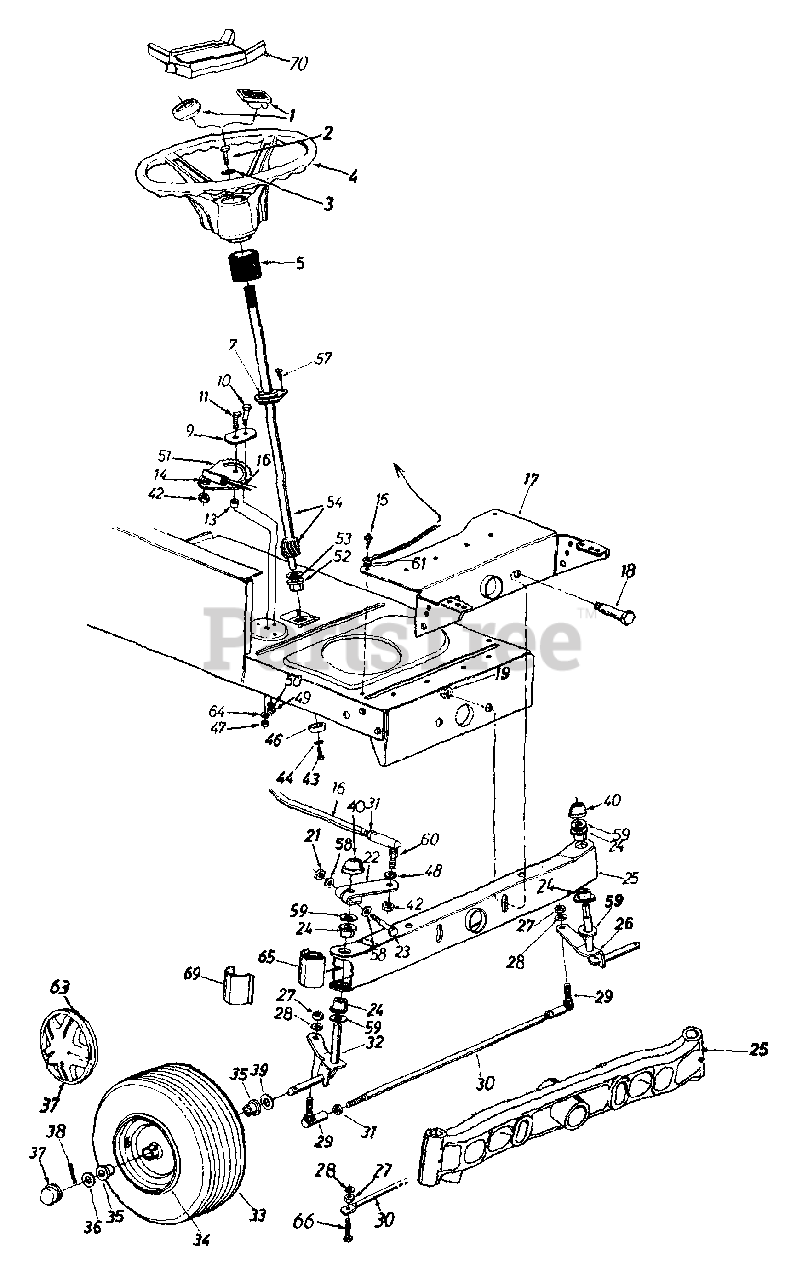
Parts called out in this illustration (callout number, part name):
1	Steering Wheel Cap
2	Hex Bolt 5/16-18 x 1" Lg.
3	Belleville Wash. .345" I.D.
4	Steering Wheel (3 Spoke)
5	Steering Bellow - 4.5"
7	Flange Bearing .628" I.D. x 1.36 O.D.
9	Retainer Plate
10	Shoulder Bolt .437 x .35 Lg. 5/16-18
11	Hex Bolt 3/8-24 x 1.0" Lg. (Gr. 5)
13	Spacer .380" I.D. x .625" O.D. x
14	L-Wash. 3/8" I.D. (H.D.)
15	Hex Wash. Hd. Self-Tap Scr.
16	Steering Drag Link
18	Shoulder Bolt
19	Flanged L- Nut 3/8-16 Thd.
21	Hex L-Nut 5/16-24 Thd.
22	Steering Arm Front Axle
23	Hex Bolt 5/16-24 x 2.00" Lg.
24	Hex Flg. Brg. .632 I.D.
26	Front Axle Ass'y. - L.H.
27	Hex Nut 3/8-24 Thd.
28	L-Wash. 3/8" I.D.
29	Ball Joint 3/8-24 Thd.
30	Tie Rod (Adjustable)
31	Hex Jam Nut 3/8-24 Thd.
32	Front Axle Ass'y. - R.H.
36	Fl-Wash. .635 I.D. x 1.59" O.D.
37	Front Wheel Hub Cap
38	Cotter Pin 1/8" Dia. x 1.25"
39	Fl-Wash. .640" I.D. x 1.24" O.D.
40	Push Cap 5/8" Dia. Rod
42	Hex Jam Nut 3/8-24 Thd.
43	Hex Patch Bolt 5/16-18 x .62"
44	Lockwasher 5/16
46	Cap
47	Hex Cent. L-Nut 3/8-24 Thd.
48	L-Wash. 3/8" I.D.
49	Hex Cent. L-Nut 5/16-18 Thd.
50	L-Wash. 5/16" I.D.
51	Steering Gear Segment
52	Hex Flg. Brg. .634 I.D.
53	Fl-Wash. (Hardened)
54	Steering Shaft
57	Oval Hd. Cr.- Sunk Scr. (Style A)
58	Wave-Wash. .32" I.D. x.62" O.D.
59	Fl-Wash. (Hardened)
60	Drag Link Ball Joint 7/16-20 Thd.
63	Spring Clip
64	Bell-Wash. .39" I.D. x 1.38" O.D.
65	Pivot Bar End Cap
66	Hex Bolt 3/8-24 x 1.5" Lg. (Gr. 5)
69	Axle Cap
70	Steering Wheel Insert
